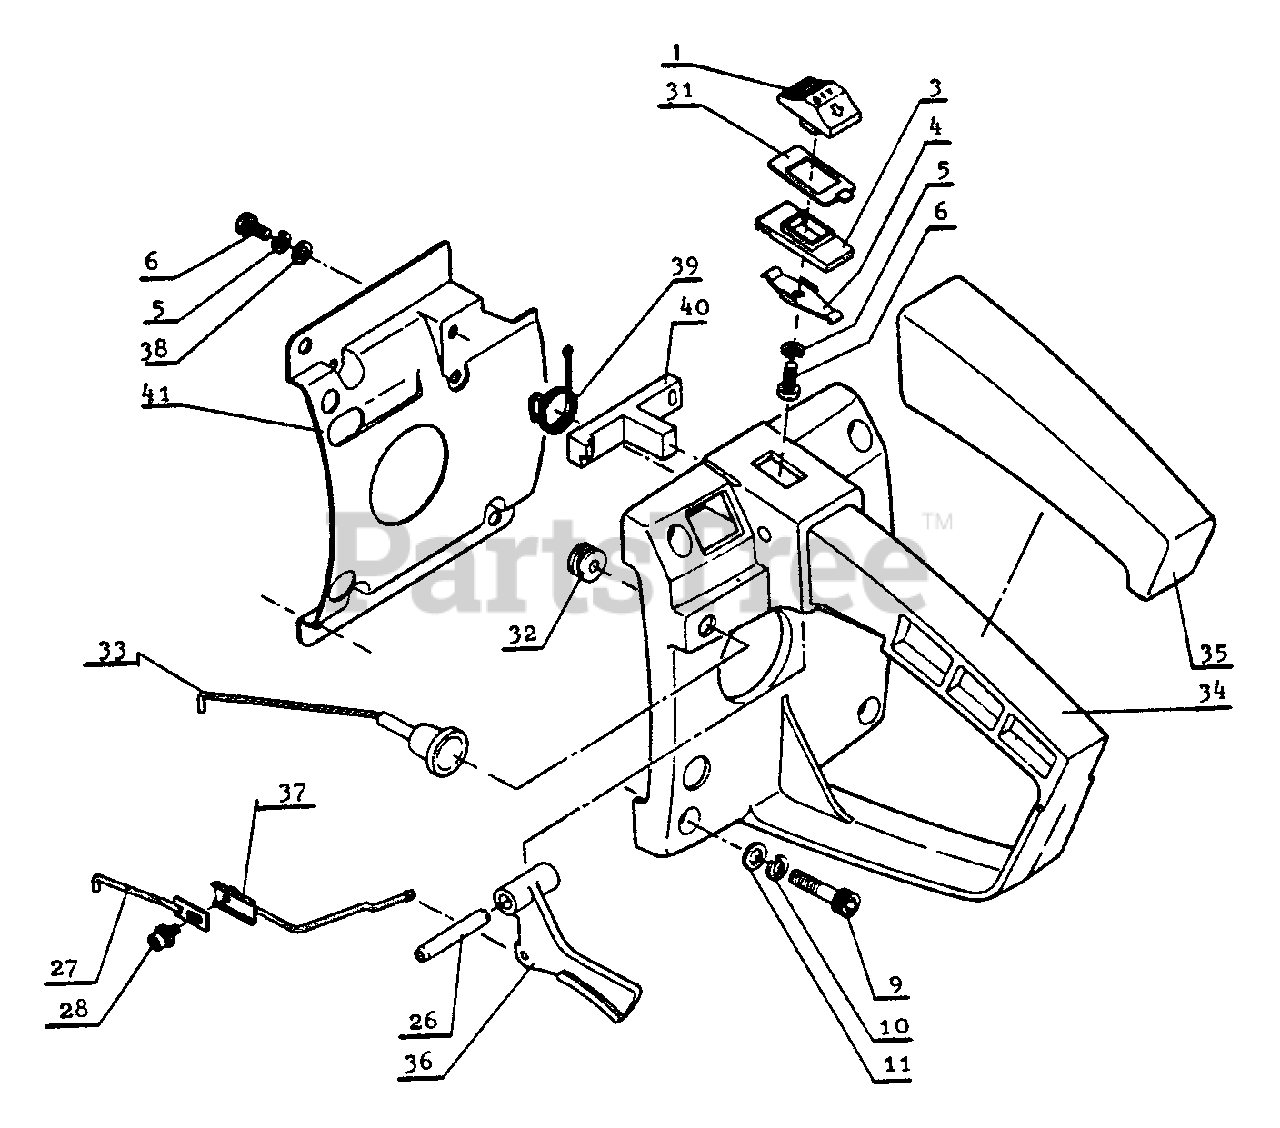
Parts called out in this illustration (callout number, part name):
1	SWITCH, IGNITION
3	GUIDE, SWITCH
4	CONTACT, SWITCH
5	WASHER, SPRING 4 MM
6	SCREW 4×10
9	BOLT 5×20
10	WASHER, SPRING 5
11	WASHER
26	PIN
27	ROD, THROTTLE - B
28	SCREW - 3×6
31	PLATE, SWITCH
32	GROMMET
33	ROD, CHOKE
34	HANDLE - REAR
35	HANDLE, REAR
36	TRIGGER, THROTTLE
37	LEVER, THROTTLE
38	WASHER 4 MM
39	SPRING
40	LEVER, DECOMPRESSION
41	COVER, ENGINE
